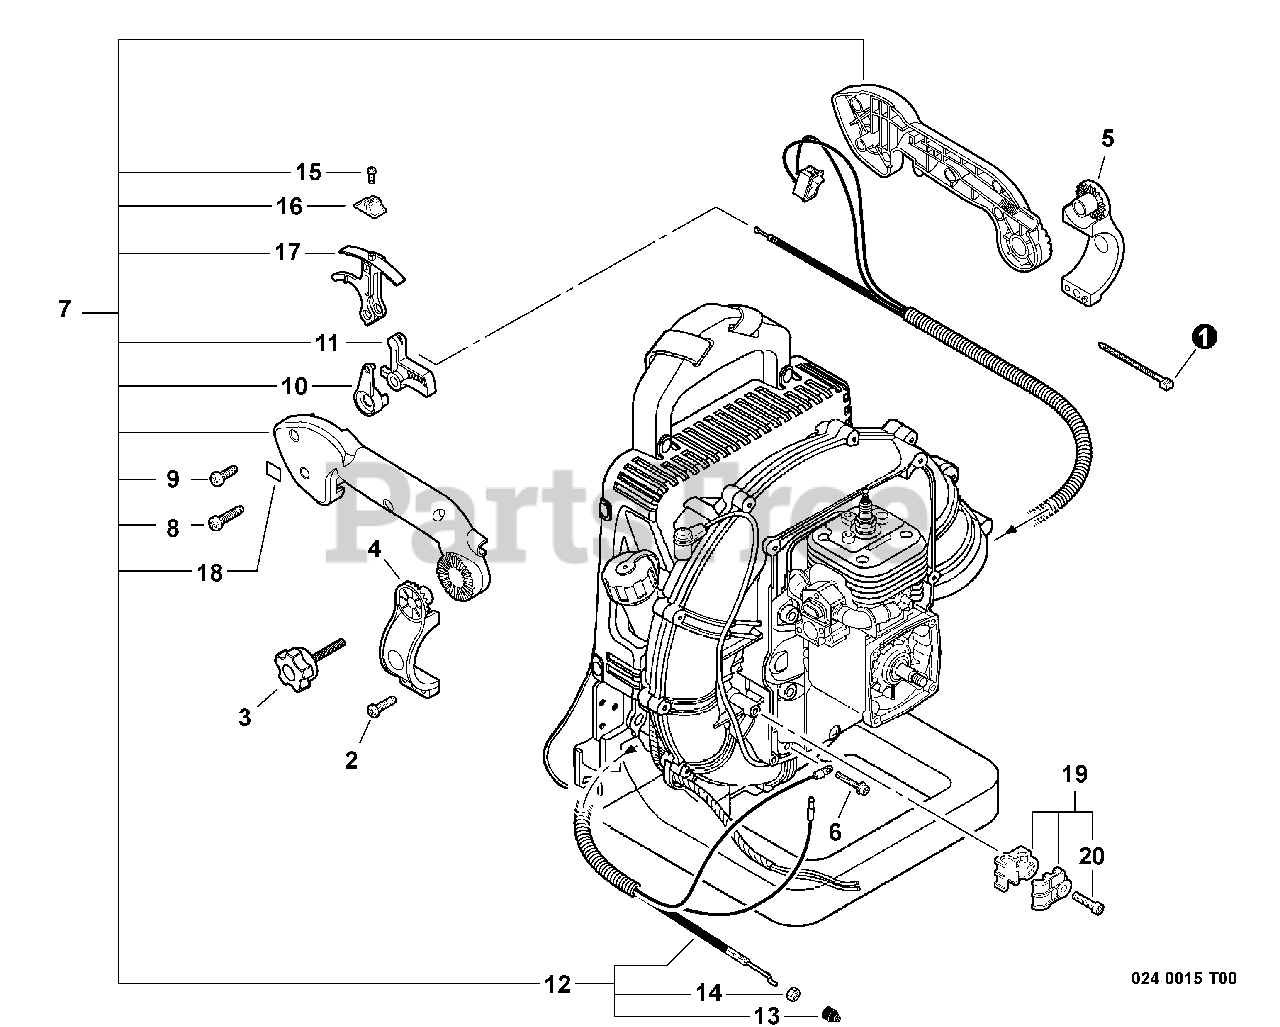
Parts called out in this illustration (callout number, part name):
1	STRAP, TIE
2	SCREW TAPPING 5×20
3	KNOB, SCREW
4	BRACKET, HANDLE - LEFT
5	BRACKET, HANDLE - RIGHT
7	THROTTLE CONTROL KIT - TUBE MOUNT
8	SCREW 5×32
10	LEVER, THROTTLE
11	TRIGGER, THROTTLE
12	CABLE ASSY, CONTROL
13	CAP, DUST
14	NUT, HEX M6
15	SCREW 3×14
17	CONTROL, THROTTLE
18	LABEL, CAUTION - IDLE
19	BRACKET KIT, CABLE
20	BOLT, TAPPING 5×25
